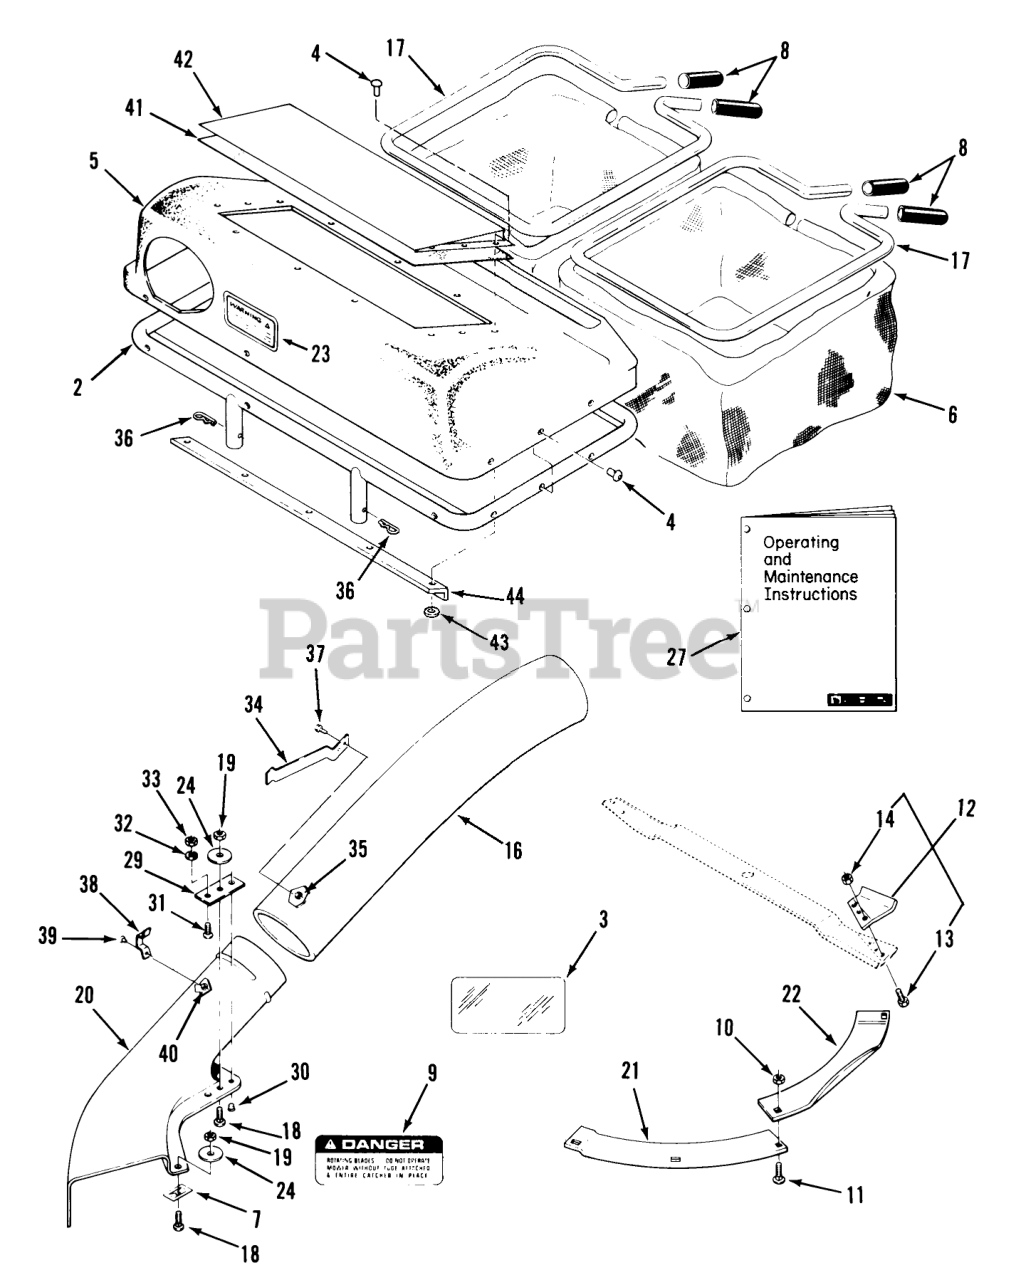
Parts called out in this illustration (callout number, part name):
2	Frame
3	DECAL-OVERLAY
4	RIVET-BLIND
5	TOP-BAGGER
6	BAG-(BLACK) W/HANDLE
7	SPEED NUT 1/4-20
8	GRIP
9	DECAL-DANGER
10	Nut
11	Bolt
12	Lift Tab Kit (includes items 13 & 14)
13	BOLT 5/16-18X5/8
14	NUT-LOCK 5/16-18
16	TUBE-BAGGER
17	Bag Frame
18	Bolt-Carriage
19	Nut
20	Elbow (includes items 29-33, 38, 39 & 40)
21	PLATE MOWER RING B (NS)
22	PLATE MOWER B
23	DECAL-WARNING
24	WASHER
27	Operating and Maintenance Instructions
29	PLATE
30	RIVET -4
31	Screw
32	Lockwasher
33	Hex Nut
34	SPRING-TUBE
35	Nut
36	Pin-Cotter
37	Screw
38	BRACKET
39	POPRIVET
40	WASHER
41	Top Screen
42	Screen Cover
43	Washer
44	Top Stiffener
